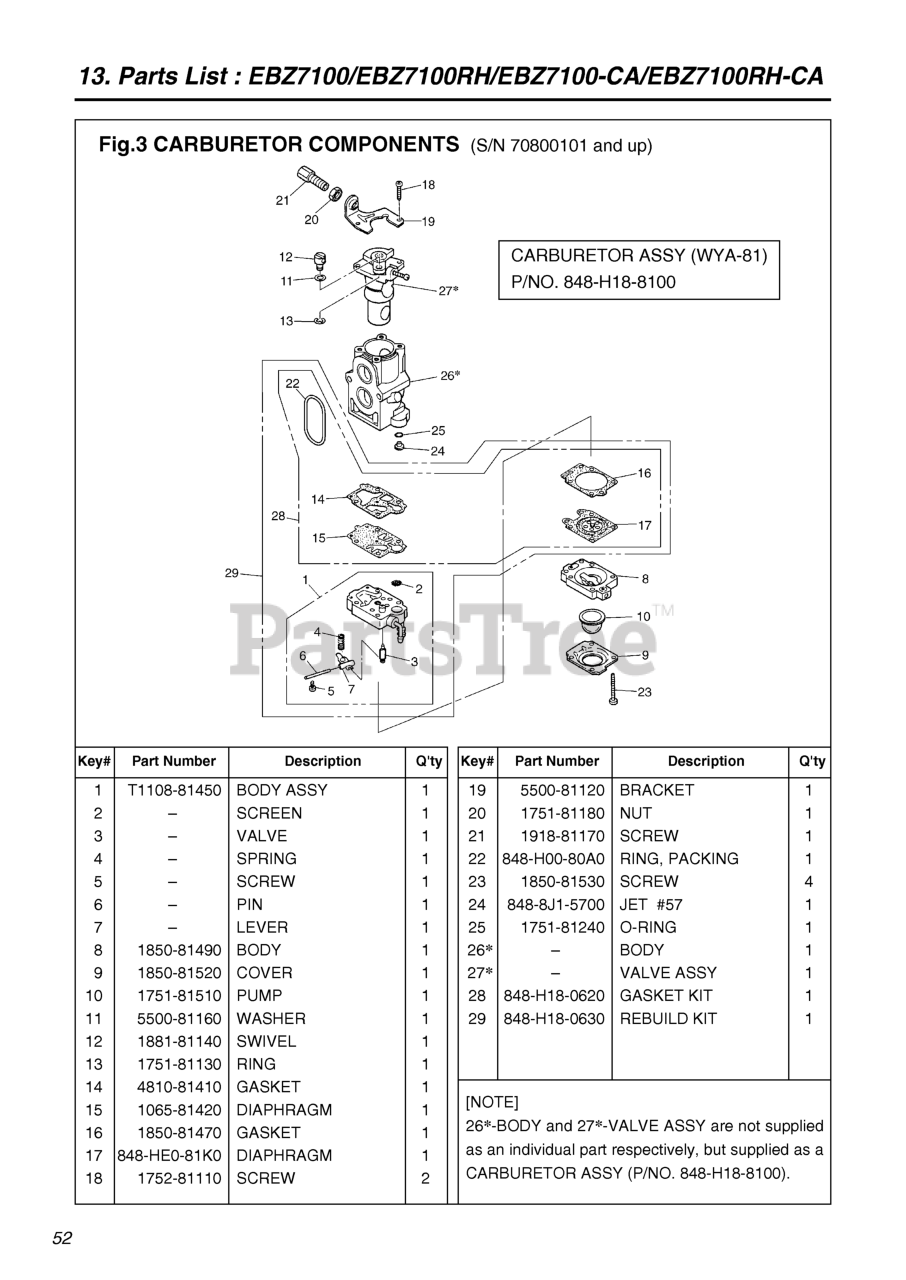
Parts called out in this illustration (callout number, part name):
1	BODY ASSY.
2	SCREEN
3	VALVE
4	SPRING
5	SCREW
6	PIN
7	LEVER
8	BODY, PURGE
9	COVER, PUMP
10	PUMP, PRIMING
11	WASHER
12	SWIVEL
13	RING
14	GASKET, PUMP
15	DIAPHRAGM
16	GASKET, DIAPHRAGM
17	DIAPHRAGM
18	SCREW
21	USE T160013170
22	RING, PACKING
23	SCREW
24	JET No.57
25	RING, O
26	CARBURETOR ASSY
27	CARBURETOR ASSY
28	GASKET KIT
29	REBUILD KIT
